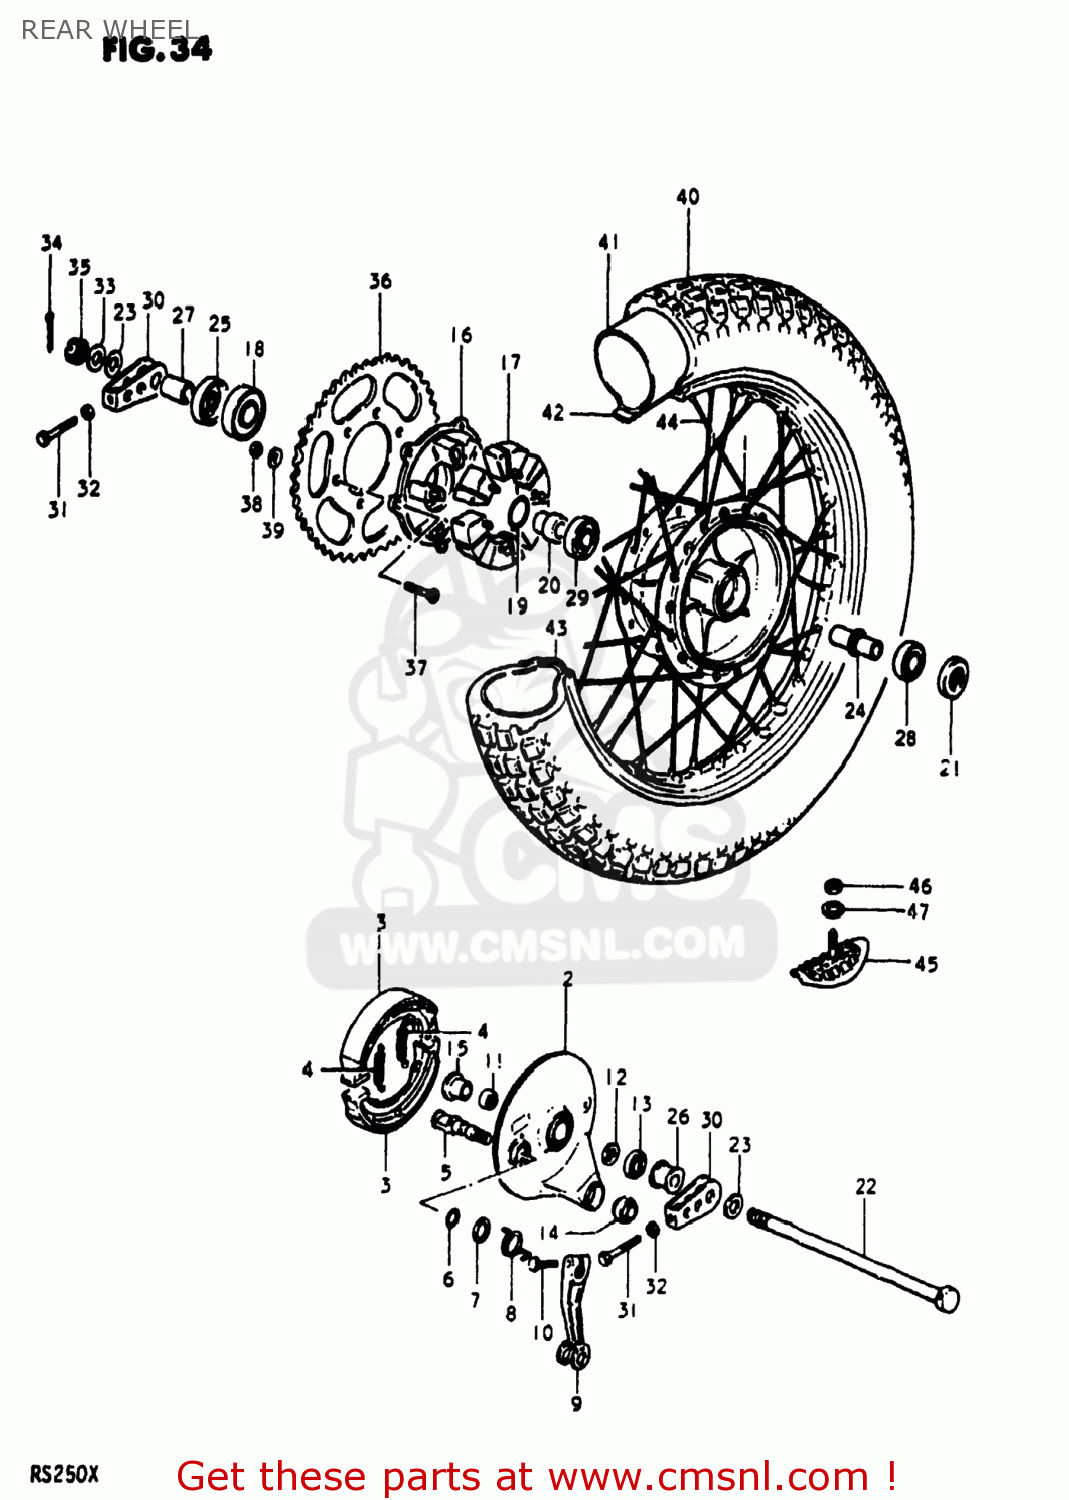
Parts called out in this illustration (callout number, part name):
1	DRUM,REAR HUB
2	PANEL,REAR HUB
3	SHOE,BRAKE (MCA)
4	SPRING
5	CAM,FRONT BRAKE
6	O-RING,BOSS
7	WASHER (15X24X1.6)
8	SPRING
9	LEVER,REAR BRAKE CAM
10	BOLT
11	BEARING(24X31X28)
12	WASHER
13	CVR,RR BRAKE AHR PNL DUST SEAL
14	SPHERICAL BEARING,TORQUE
15	SPACER,REAR HUB PANEL
16	DRUM,REAR SPROCKET MOUNT
17	ABSORBER,RR HUB SHOCK
18	BEARING
19	O-RING
20	SPACER,REAR SPROCKET DRUM
21	OIL SEAL
22	AXLE,REAR
23	WASHER (17X30X3.2)
24	SPACER,REAR HUB BEARING
25	SEAL,OIL(30.5X52X8)
26	SPACER,REAR AXLE,RIGHT
27	SPACER(17X30.5X16.3)
28	BEARING
29	BEARING
30	ADJUSTER,CHAIN
31	BOLT
32	NUT
33	WASHER
34	PIN,COTTER
35	NUT
36	SPROCKET,REAR (NT:52)(AL)
37	SCREW(8X33.5)
38	NUT
39	WASHER
40	TIRE
41	TUBE ASSEMBLY,WHEEL,INNER
42	PROTECTOR,WHEEL,INNER
43	RIM,REAR WHEEL
44	SPOKE SET,REAR
45	STOPPER,BEAD
46	NUT
47	WASHER
